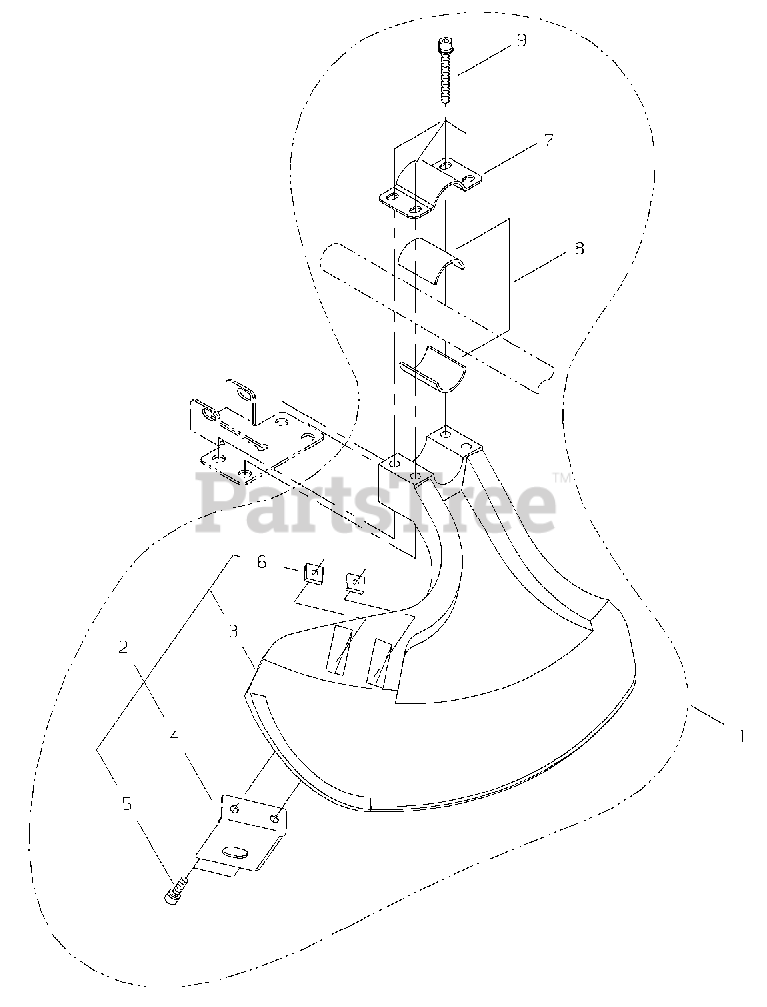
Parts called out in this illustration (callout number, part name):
2	DEBRIS SHIELD ASSY
3	SHIELD
4	SCREW - 5X16
5	KNIFE, TRIMMER LINE
6	NUT - 5
7	CLAMP - UPPER
8	SPACER
9	SCREW - 5X45
